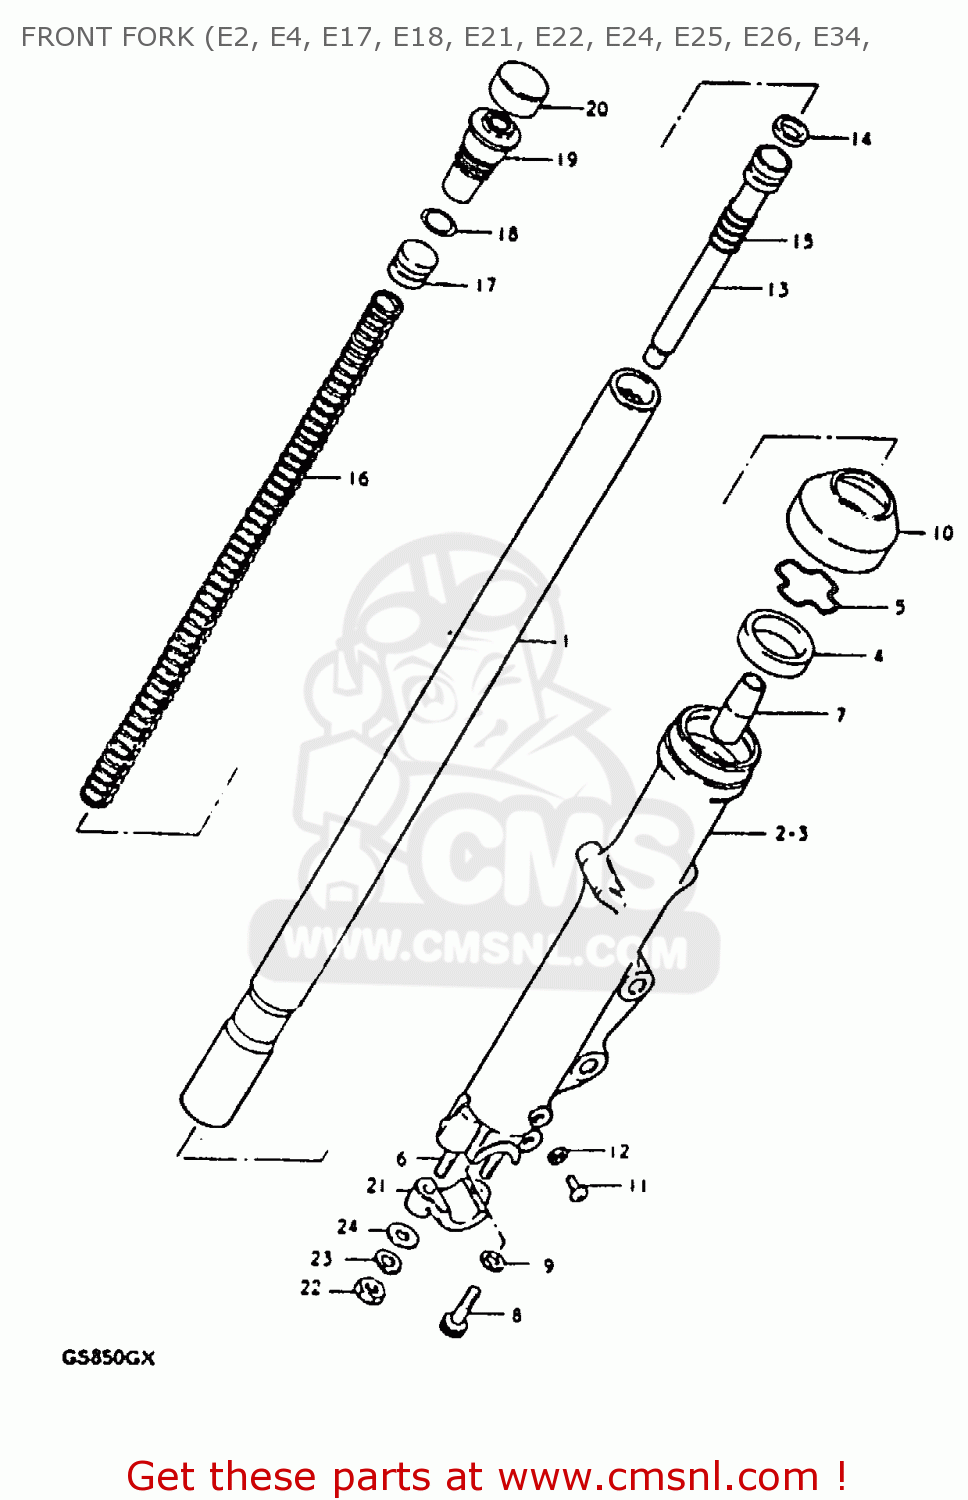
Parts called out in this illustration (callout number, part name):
1	INNER TUBE
2	TUBE,FORK,OUTER,RIGHT
3	TUBE,FORK,LEFT,OUTER
4	OIL SEAL,FRONT FORK
5	RING,STOPPER
6	STUD BOLT
7	PIECE,OIL LOCK
8	BOLT,FORK CYLINDER(10X25)
9	GASKET (NAS)
10	SEAL,DUST
11	SCREW
12	GASKET,DRAIN,PLUG (NAS)
13	CYLINDER,FRONT FORK
14	RING,PISTON
15	SPRING,REBOUND
16	SPRING
17	PISTON,FREE
18	O-RING
19	CAP, UPPER
20	CAP
21	HOLDER,AXLE
22	NUT (8MM)
23	LOCK WASHER
24	WASHER
